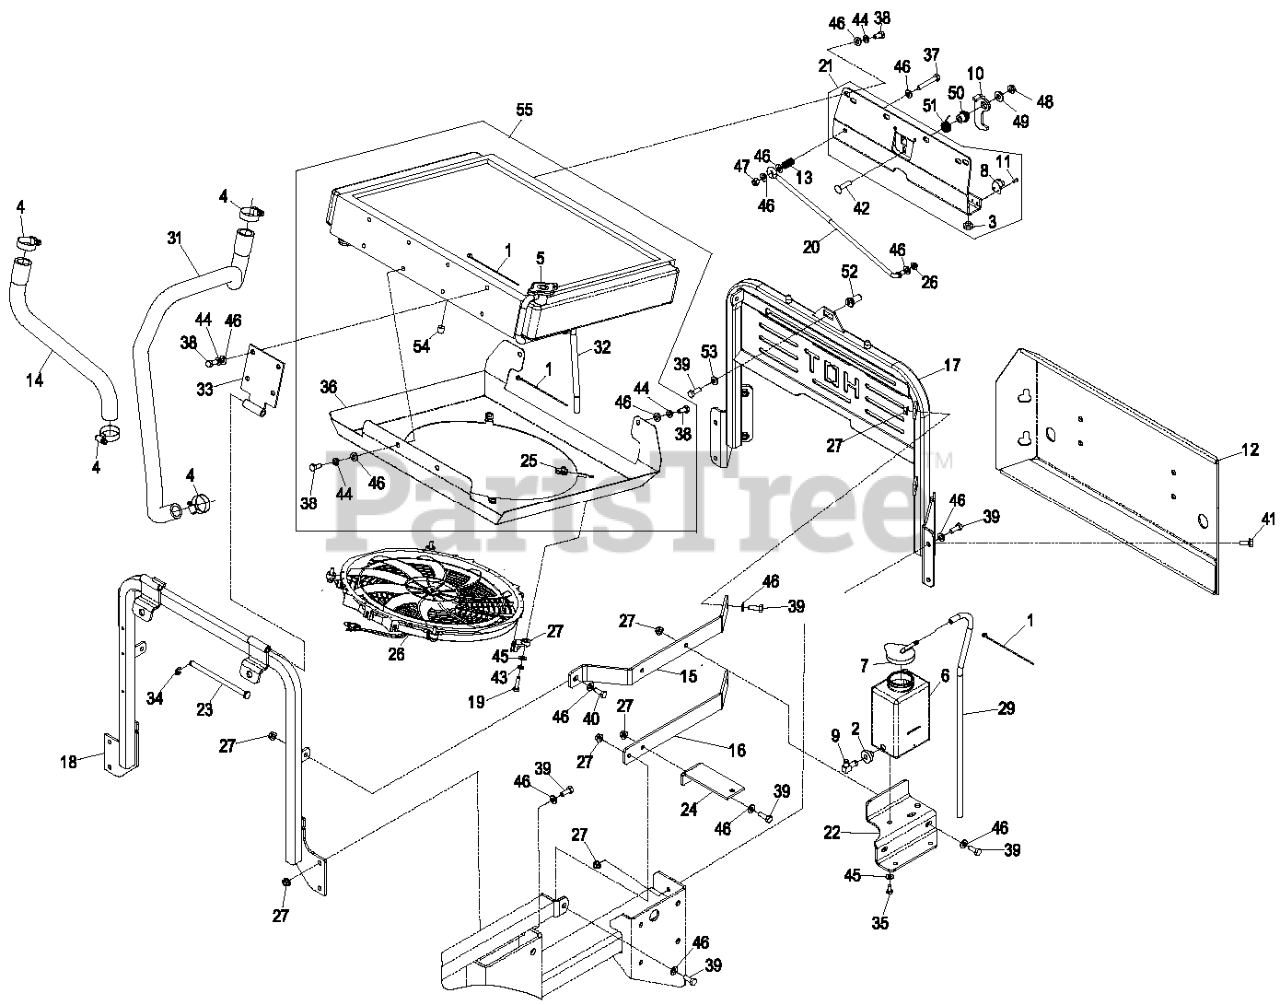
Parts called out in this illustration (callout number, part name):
1	TIE-CABLE
5	CAP-RADIATOR
6	TANK-OVERFLOW
7	CAP-TANK, OVERFLOW
10	HOOK,LATCH
12	WLD,REAR BUMPER
13	SPRING,LOCK PIN
14	HOSE,RADIATOR UPPER D902(
16	RIB, BOTTOM
17	WLD,REAR GUARD
18	ASM, RAD. MOUNT W/ DECALS
19	SCREW-HH
20	ROD,PROP
21	ASM,LATCH PLATE S.O.
22	BRACKET,BOTTLE
24	BRACKET, HYDRAULIC TANK
25	Nut, Retainer Panel
28	KIT,16' FAN SERVICE
30	MOUNT,FAN
31	HOSE,RADIATOR LOWER D902
32	HOSE,OVERFLOW
33	WLD,HINGE PLATE
35	SCREW-HH
36	SHROUD,FAN
37	SCREW-HH
38	SCREW-HH
39	SCREW-HH
40	SCREW-HH
41	SCREW-HHF
42	SCREW-CARR
43	SCREW-HH
44	WASHER-LOCK
45	WASHER-FLAT
46	WASHER-PLAIN
47	NUT-LOCK, NI
49	WASHER-FLAT
50	BUSHING-LATCH, SEAT
51	SPRING,LATCH
52	PIN,LATCH
53	WASHER-SPRING
54	PLUG-PIPE
